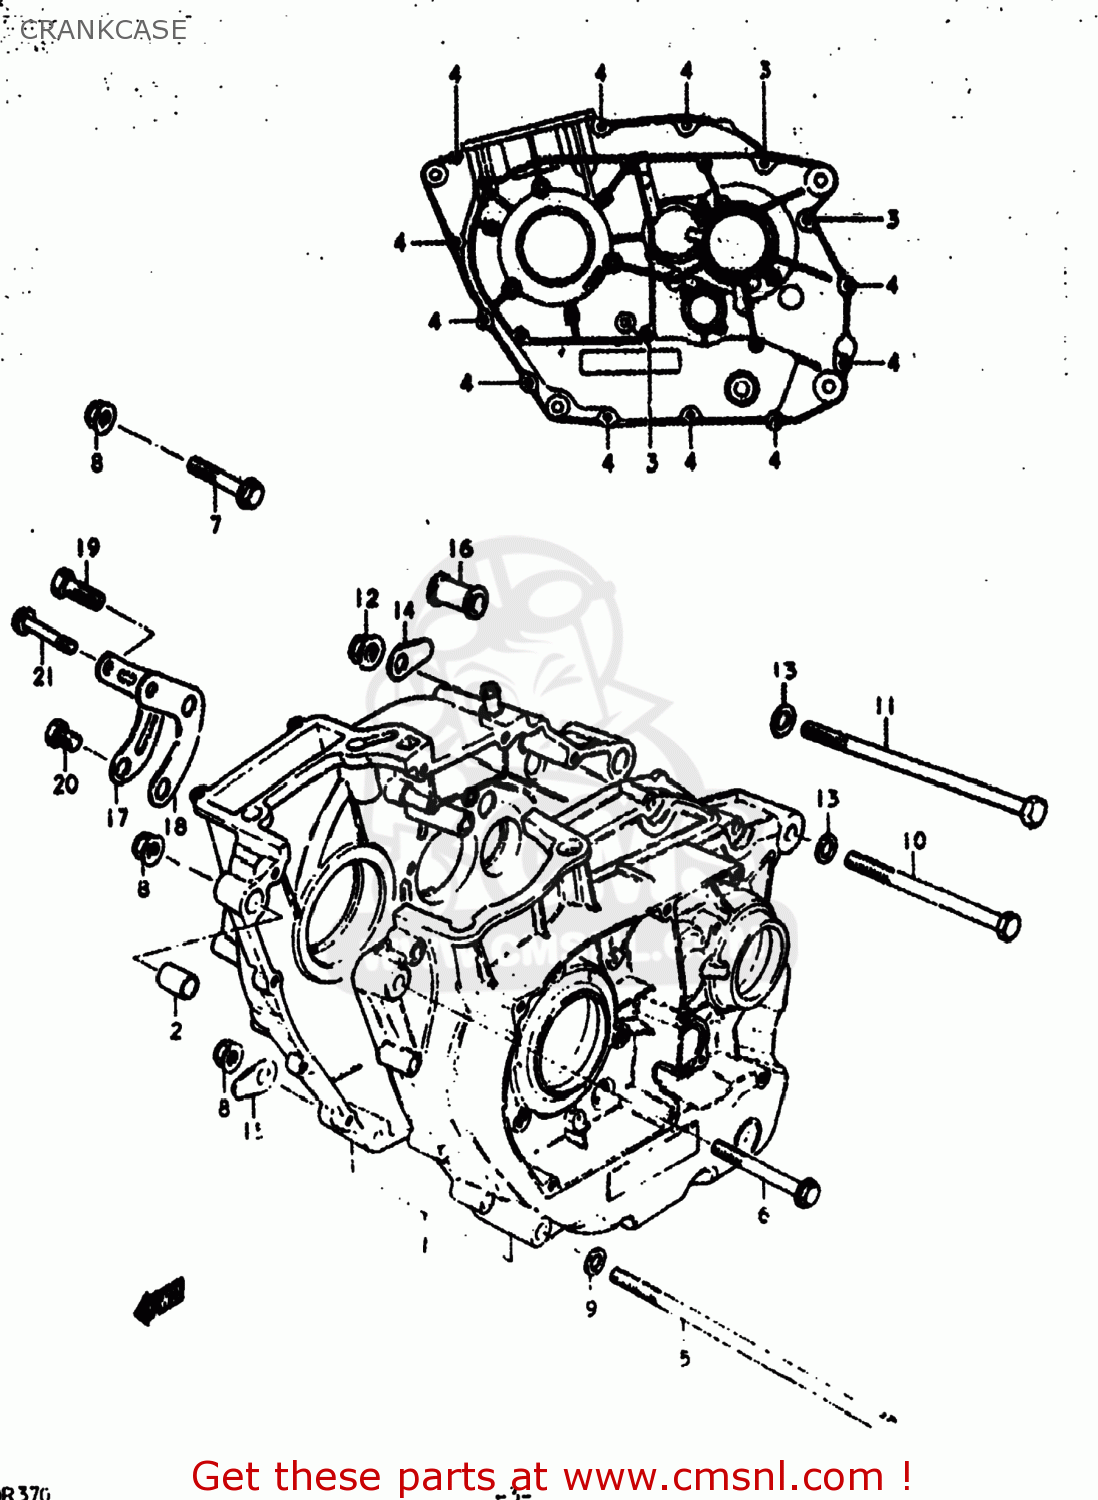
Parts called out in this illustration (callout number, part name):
1	CRANKCASE SET
2	PIN
3	SCREW
4	SCREW (6X35)
5	BOLT
6	BOLT (8X70)
7	BOLT
8	NUT
9	WASHER
10	BOLT
11	BOLT 10X155
12	NUT
13	WASHER
14	WASHER
15	WASHER
16	SPACER
17	CAP,OIL GALLERY
18	GASKET,OIL GALLERY (MCA)
19	BOLT UNION
20	PLUG
21	BOLT
